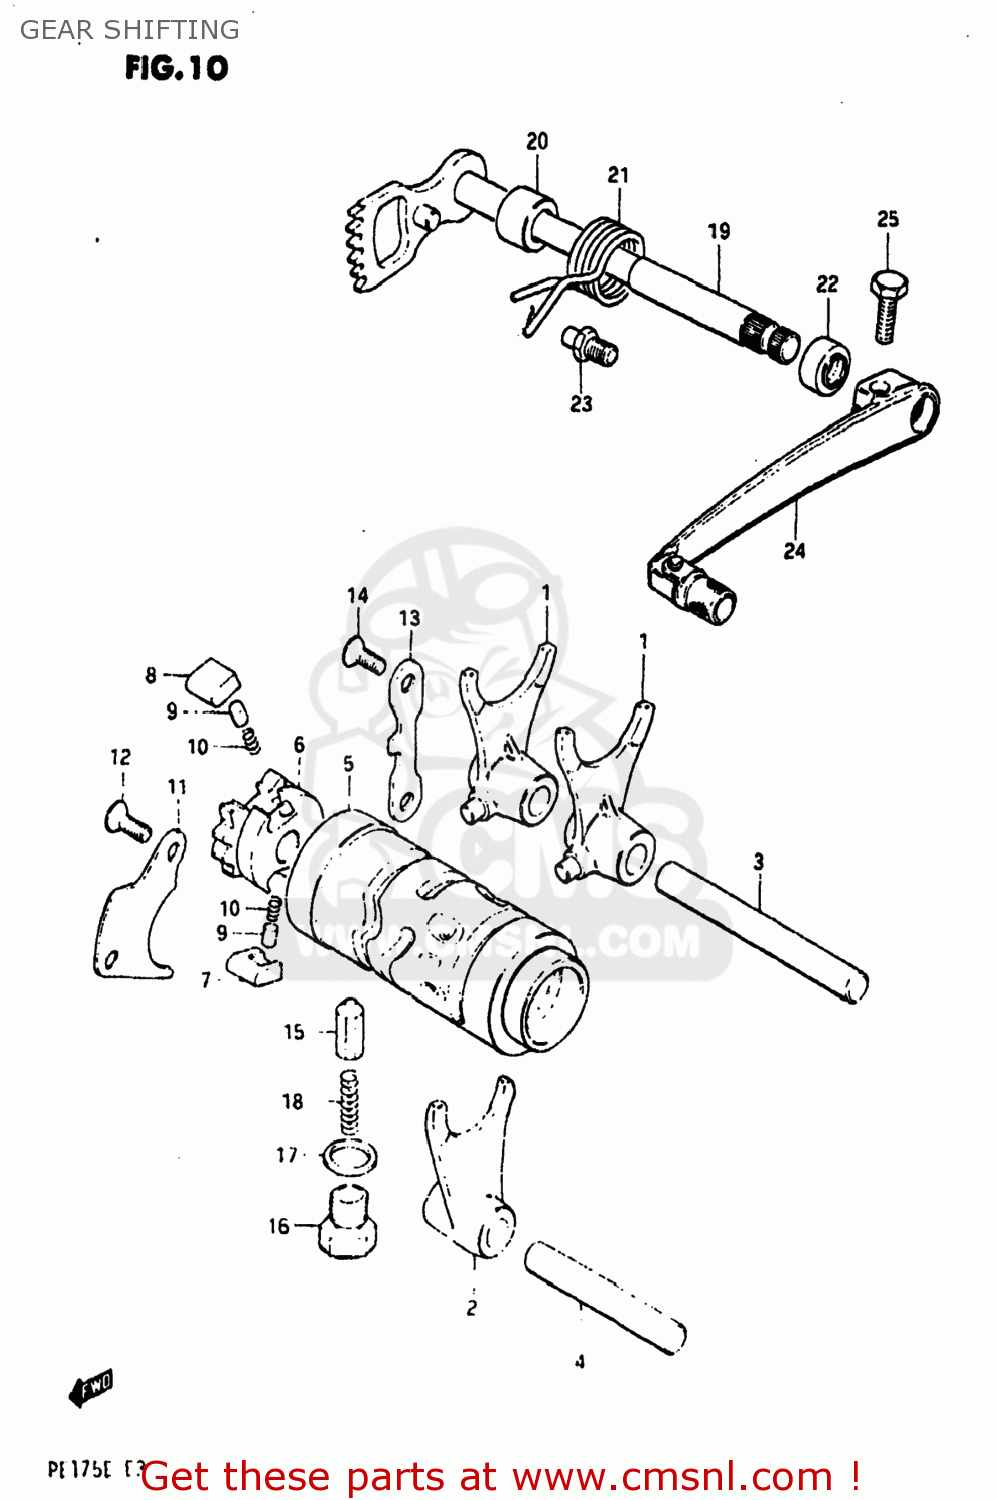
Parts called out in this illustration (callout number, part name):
1	FORK,GEAR SHIFT NO.1
2	FORK,GEAR SHIFT NO.2
3	SHAFT,GEAR SHIFT FORK
4	SHAFT,GEAR SHIFT FORK
5	CAM,GEAR SHIFT
6	SHIFTER,GEAR SHIFT CAM
7	PAWL,GEAR SHIFT NO.1
8	PAWL,GEAR SHIFT NO.2
9	PIN(5X8)
10	SPRING
11	LIFTER,GEAR SHIFT PAWL
12	SCREW
13	GUIDE,GEAR SHIFT CAM
14	SCREW
15	STOPPER,GEAR SHIFTING
16	HOUSING,GEAR SHIFT CAM STOPPER
17	GASKET(14X19.2X2) (NAS)
18	SPRING
19	SHAFT,GEAR SHIFT
20	SPACER(12X20X15.3)
21	SPRING
22	OIL SEAL
23	STOPPER,GEAR SHIFT CAM
24	LEVER,GEAR SHIFT
25	BOLT
